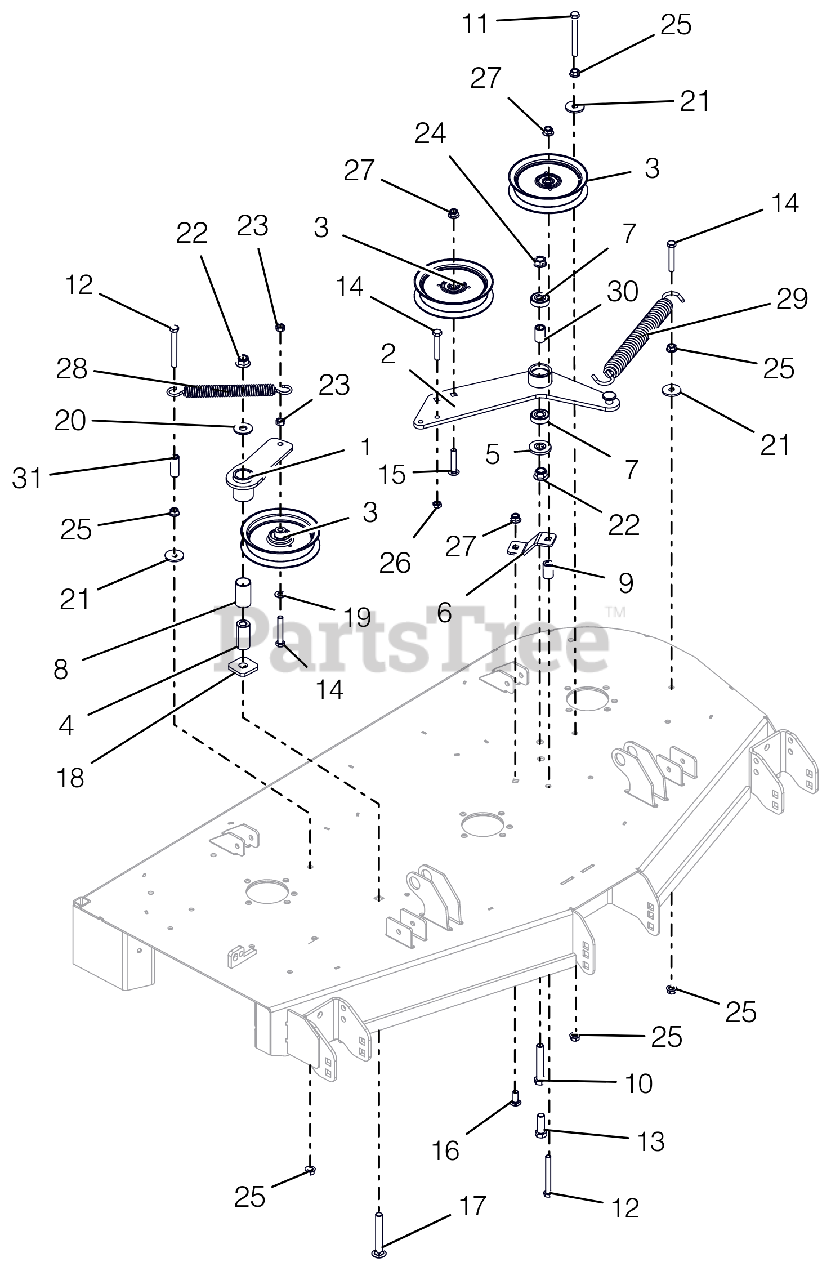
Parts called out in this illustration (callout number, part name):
1	WMT, IDLER ARM - BLACK
2	DECK PTO IDLER ARM WLDMT - BLK
3	IDLER, FLAT 5.00"
4	BSHG, SPCR .502X.997X2.03 PM
5	SPACER, IDLER ARM
6	PTO FIXED IDLER MTG BRKT-ORG
7	BRG-BALL .500X1.38X.437
8	BSHG, 1.00X1.125X1.937
9	BUSHING, SLV .380X.750X1.190
10	@BLT-HEX .50-13X3.00 GR5 YWZC
11	@BLT-HEX .38-16X3.50 GR5 YWZC
12	@BLT-HEX .38-16X3.25 GR5 YWZC
13	@BLT-HEX .50-13X1.50 GR5 YWZC
14	@BLT-HEX .38-16X2.25 GR5 YWZC
15	BLT-RDHDSQNK .38-16X2.00 SHTYW
16	@BLT-RDHDSHSQNK.38-16X1.0 G5YZ
17	@BLT-RDHDSQNK .50-13X3.50 G5YZ
18	WSHR-FLT .640X1.75X.250
19	@WSHR-FL-STL.406X.812X.065 YWZ
20	@WSHR-FL-STL.563X1.38X.109YWZC
21	WSHR-FL-STL .406X1.375X.135 YZ
22	@NUT-LK-NYL-FLG .50-13 YWZC
23	@NUT-LK-CTR .38-16 YWZC
24	NUT-LK-CTR-FLG .50-13 YWZC
25	@NUT-SPNLK-FLG .375-16 YWZC
26	NUT-HEX-JAM .375-16 YWZC
27	@NUT-LK-NYL-FLG .38-16 YWZC
28	SPRING, EXTENSION
29	SPRING, EXTENSION
30	SPACER .510 X .75 X 1.1485
31	SPACER, .375IDX.625ODX1.66 PM
